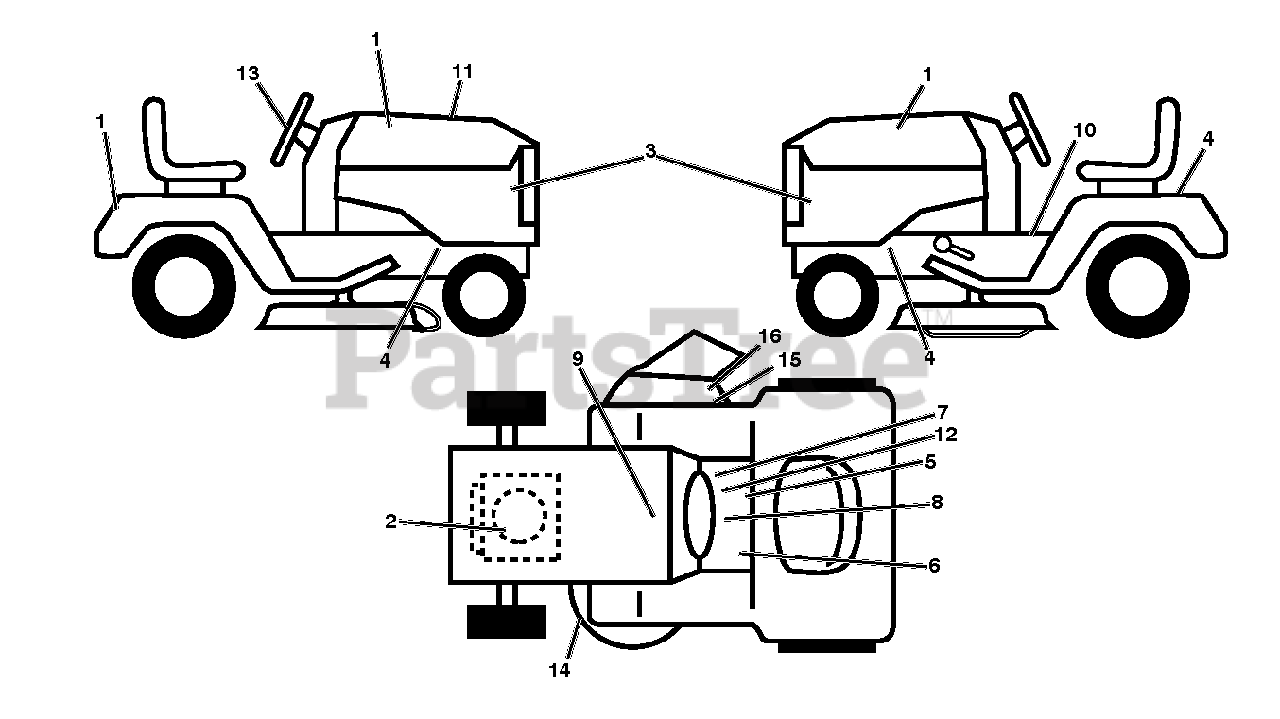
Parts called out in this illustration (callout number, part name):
1	DECAL, DIXON LOGO, DOMED
9	DECAL BTRY SYMBOLS
13	DECAL.WHEEL.STEER.DIXON
14	DECAL.MOWER.SCH.48/54
15	DECAL, DEFLECT WARNING
